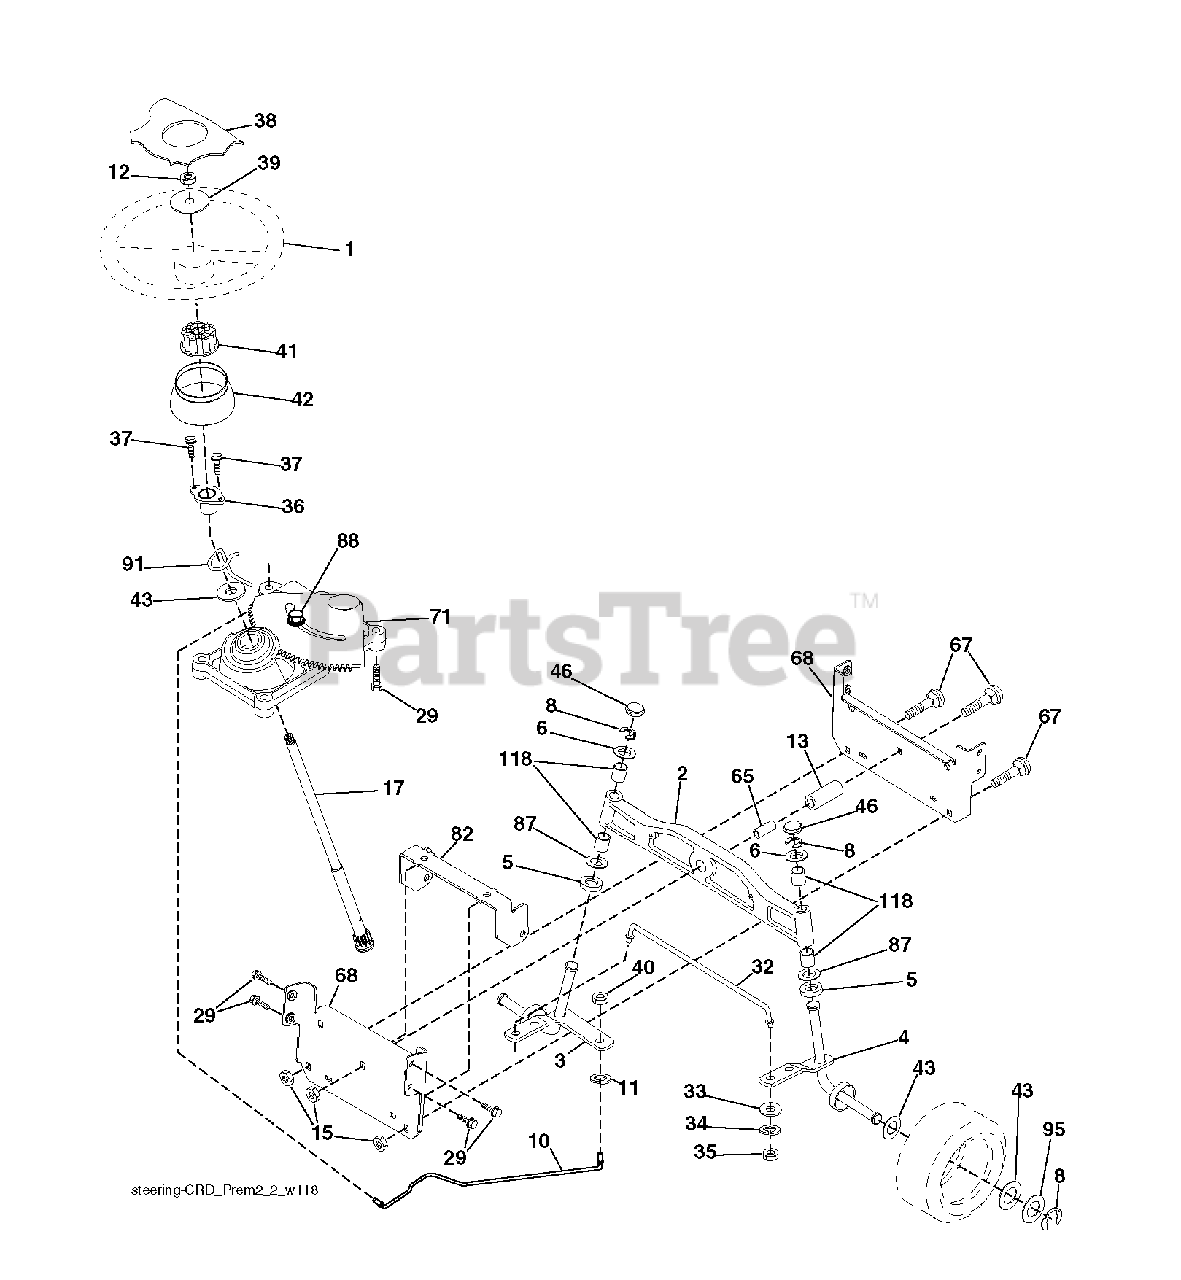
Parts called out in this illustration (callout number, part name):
1	WHEEL.STEERING.PREM.2.BLK
2	AXLE ASSY FRONT
3	SPINDLE.ASM.LH.15"TIRES
4	SPINDLE.ASM.RH.15"TIRES
8	RING CLIP
10	DRAGLINK.15".TIRES.2001
11	WASHER, LOCK 3/8
12	NUT.HEX.1/2-20
13	TUBE, PIVOT AXLE
15	NUT
17	SHAFT ASM STRG
29	SCREW, 3/8-16X3/4
33	WASHER M
34	LOCKWASHER
35	NUT, CROWNLOCK
36	BUSHING, STRG. BLK
38	INSERT.CAP.STRG.WH.BLACK
39	WASHER 9/16"ID, 2 3/8"OD
40	NUT CROWNLOCK 3/8-24
41	ADAPTER, WHEEL STNG..
46	CAP.SPINDLE
65	SPACER BRACE AXLE
67	BOLT CARRIAGE
68	BRACE.AXLE.15"TIRES
71	STEERING ASM
82	BRACKET.SUSP.CHASSIS.FRONT.15
87	WASHER, FLAT .781 X 1 1/2"
88	BOLT, SHOULDER 7/16-20
91	CLIP.STEERING
95	WASHER.HARDENED
118	BUSHING, AXLE CAST
